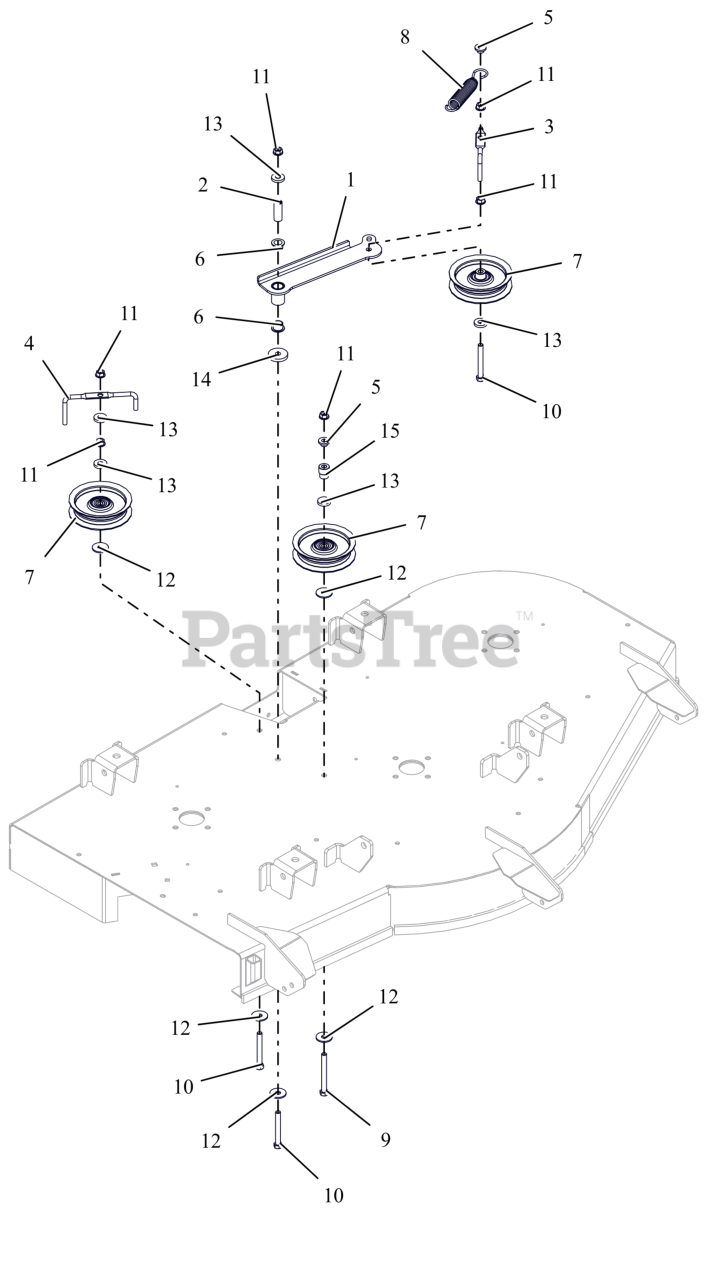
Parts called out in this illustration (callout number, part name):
1	WLDMT, IDLER ARM-52"
2	SPACER, .375IDX.625ODX1.66 PM
3	WIREFORM, BELT FINGER
4	BELT FINGER
5	BSHG-FLG .385X.500X.875X.406
6	BSHG-FLG, .625X.750X.500X1.00
7	IDLER, FLAT - 4.06" X .75"
8	SG-TENS .135X.98X6.0 WLD 62
9	BLT, HEX .38-16X3.50 G5 ZCC
10	BLT, HEX .38-16X3.00F G5 ZCC
11	NUT-LK-CTR-FLG .375-16 GF ZCC
12	WSHR FL STL .406X1.25X.10ZC120
13	WSHR, FLT .406X1.00X.188 ZCC
14	WSHR, FLT .406X1.50X.245 ZCC
15	BUSHING, IDLER (P/M)
